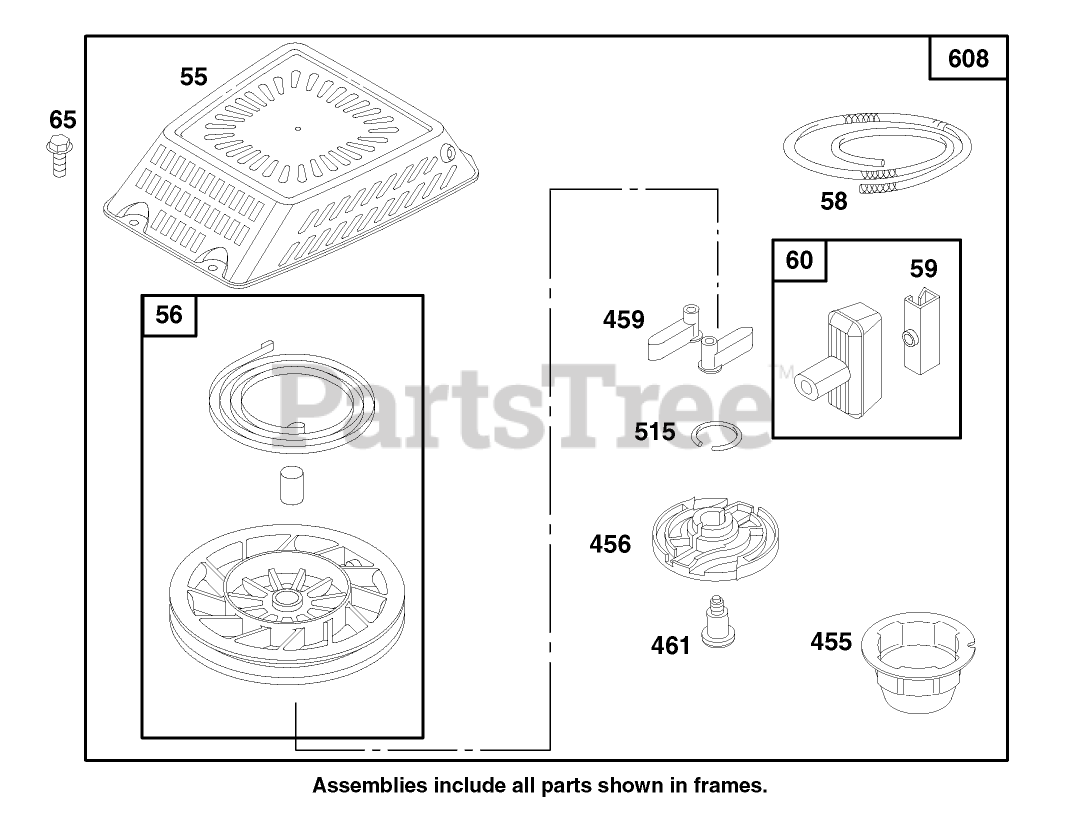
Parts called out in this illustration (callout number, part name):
56	PULLEY-STARTER, REWIND
58	ROPE-STARTER
59	INSERT-HANDLE, REWIND
455	CUP - STARTER
456	RETAINER-STARTER, REWIND
459	PAWL-STARTER
515	SPRING-TORSION
608	BRIGGS #498146
